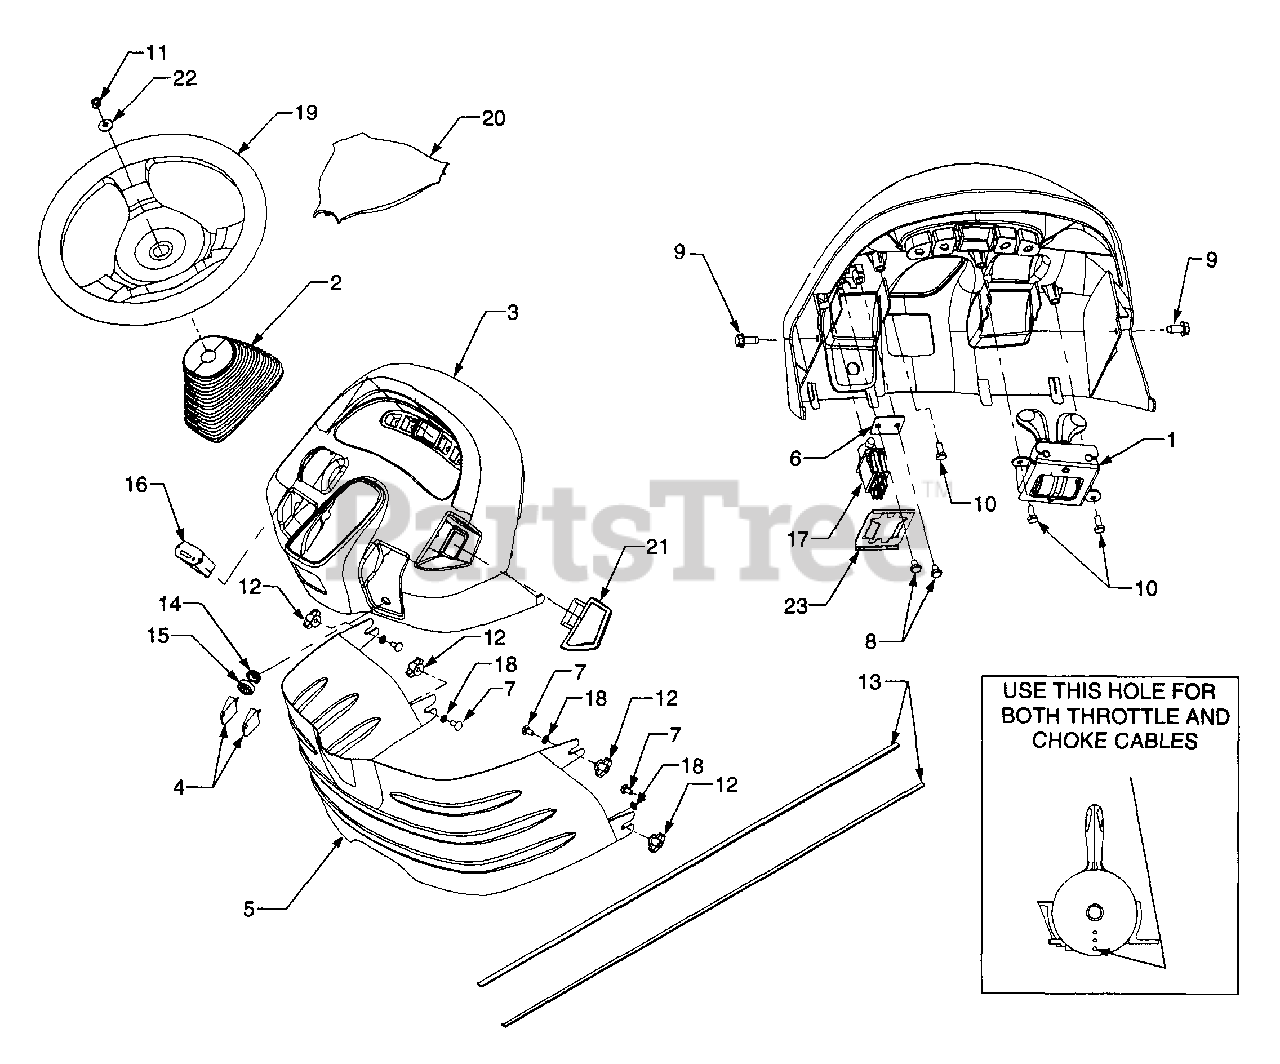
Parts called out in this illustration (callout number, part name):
1	Control Assembly, Throttle/Choke
2	Boot, Tilt Steer
3	Dash Panel
4	Key, Ignition (Set of 2)
7	Carriage Bolt, 1/4-20 x .62
8	Screw, Hex Cap 1/4-20 x .375 GR5
9	Screw, Hex Wash. Hd. Tapp 5/16-18 x .75
10	Screw, Hex Cap 1/4-20 x .50 GR5
11	Nut, Hex Lock, 5/16-24
12	Wing Nut, 1/4-20 w/Bell Washer
13	Seal, Screen
14	Nut, Ignition Switch, 5/8-32
15	Cap, Ignition Switch
16	Hour Meter
17	Switch, PTO
18	Nut, Push
19	Steering Wheel
20	Cover, Steering Wheel
21	Handle, PTO Switch
22	Washer, Belleville, .34 x .872
23	Bracket, PTO Switch Retainer
